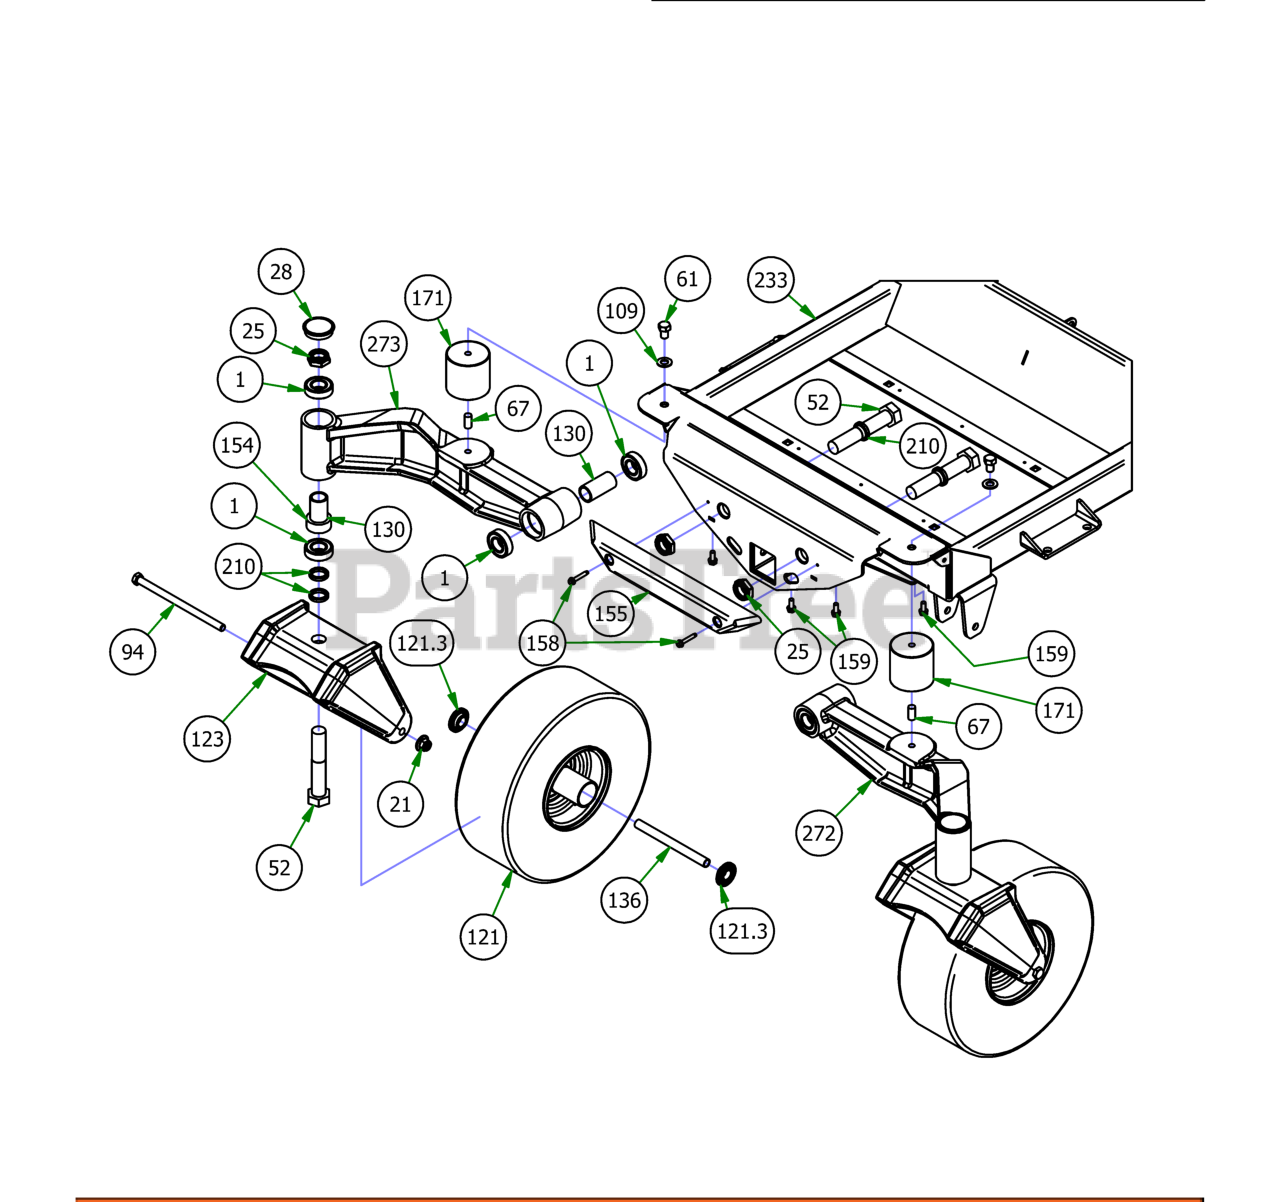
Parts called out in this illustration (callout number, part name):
1	1641 BEARING W/2 CONTACT RUBBER SEALS
21	1/2-13 NYLON INSERT FLANGE LOCKNUT ZINC
25	1" Fine Thread 1/2 Nylock Nut
28	2017 Bearing Cover
52	1-14 x 5.5 Hex Bolt Grade 8 Zinc Yellow
61	1/2" x 3/4" Hex Bolt
67	1/2-13 x 1" Stud
94	1/2" x 9" GR 5 Hex Bolt
109	1/2" Washer (Grade 8)
121	2019 15x6.00-6 Non Pneumatic Black Front Assembly
121.3	1-3/4" Bearing-Large Bore Front Rim
123	2020 R Series Cast Front Fork
130	2016 Front Bearing Spacer
136	Front Wheel Spanner
154	Rubber Stabilizer (Front Forks) [R series]
155	2017 XP Bumper
158	1/4" x 1 1/2" Self Tapping Screw
159	5/16 x 3/4 washer head type F screw
171	Vibration Mount-Blue Dot
210	Spacer, 1x1.375x.25
233	2019 Renegade Diesel Frame - Powdercoated
272	2019 Front I-Beam Left
273	2019 Front I-Beam Right
